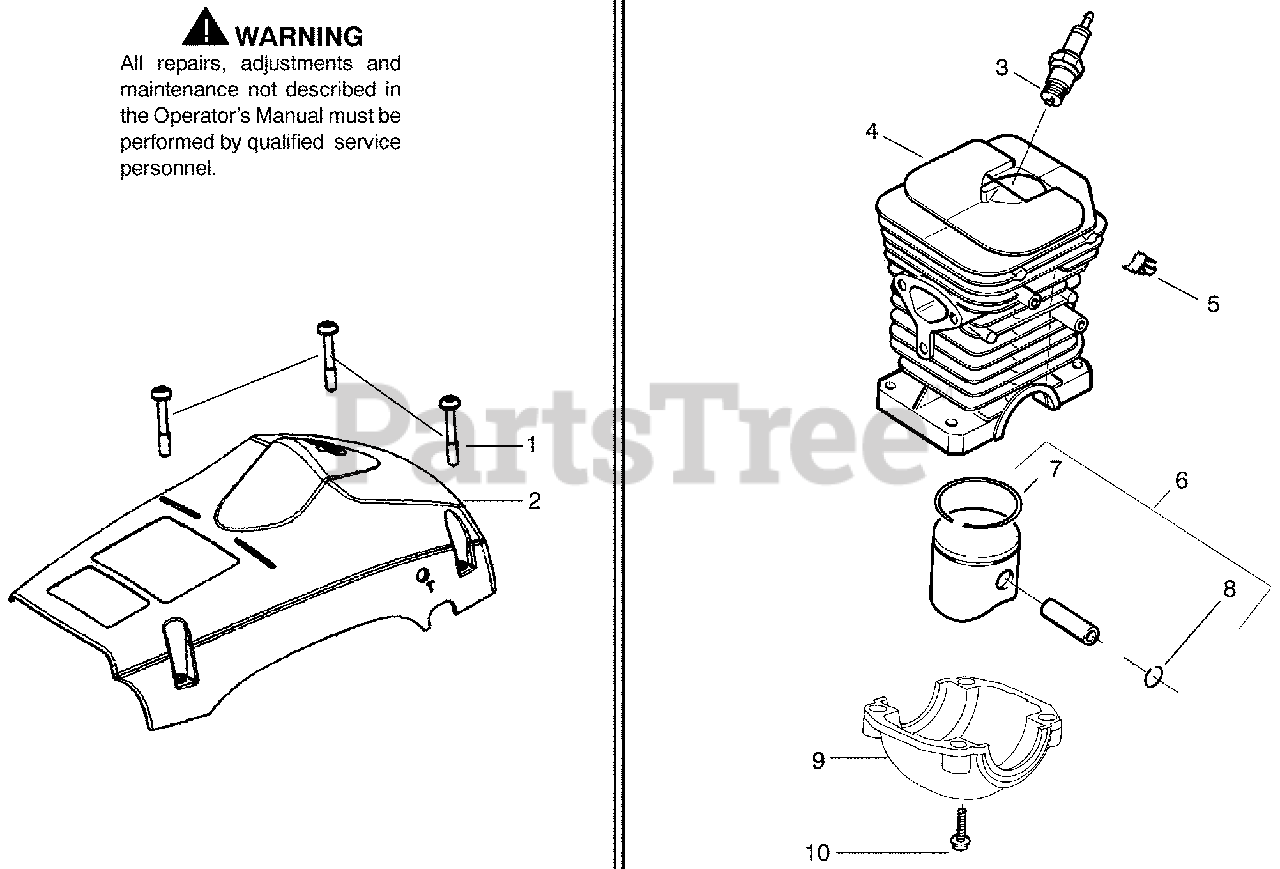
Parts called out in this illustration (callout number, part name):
2	Shield--Cylinder
3	Spark Plug (RCJ--7Y)
4	Kit--Cylinder (40cc)
5	Clip -- High Tension Lead
6	Kit--Piston (40cc)
7	Ring--Piston (40cc)
8	Piston Pin Retainer
9	Cap--Crankcase
